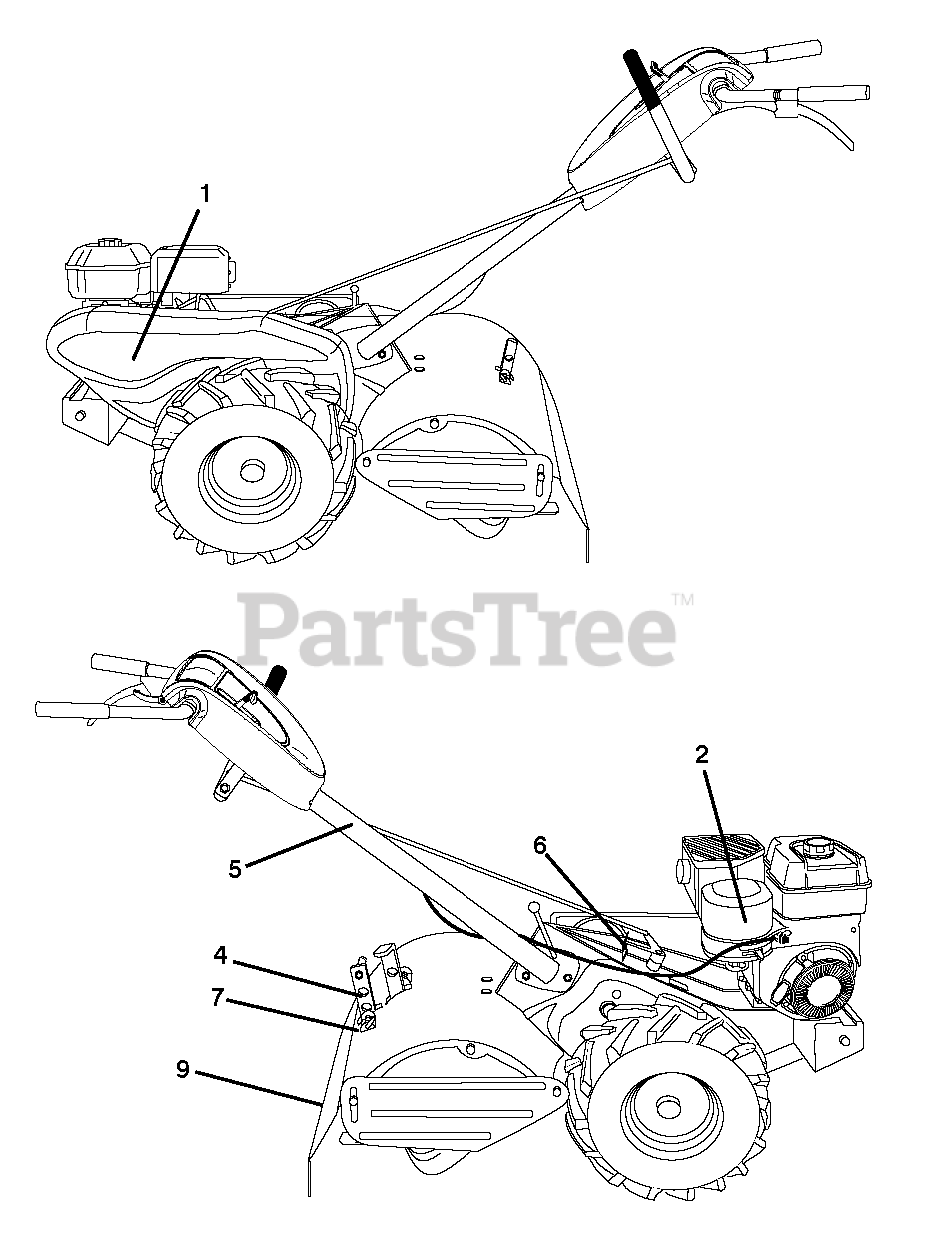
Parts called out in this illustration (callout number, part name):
1	RP.DECAL.BADGE.170MM.TEXTLOGO
2	DECAL.B&S.950S
4	DECAL.TINE.SHIELD.CRT.17".HUSQ
5	DECAL TI (2 2)
6	DECAL.SHIFT.INDICATOR.TILLER
7	DECAL.WARNING.SHLD.ENG/FR
9	DECAL TI
